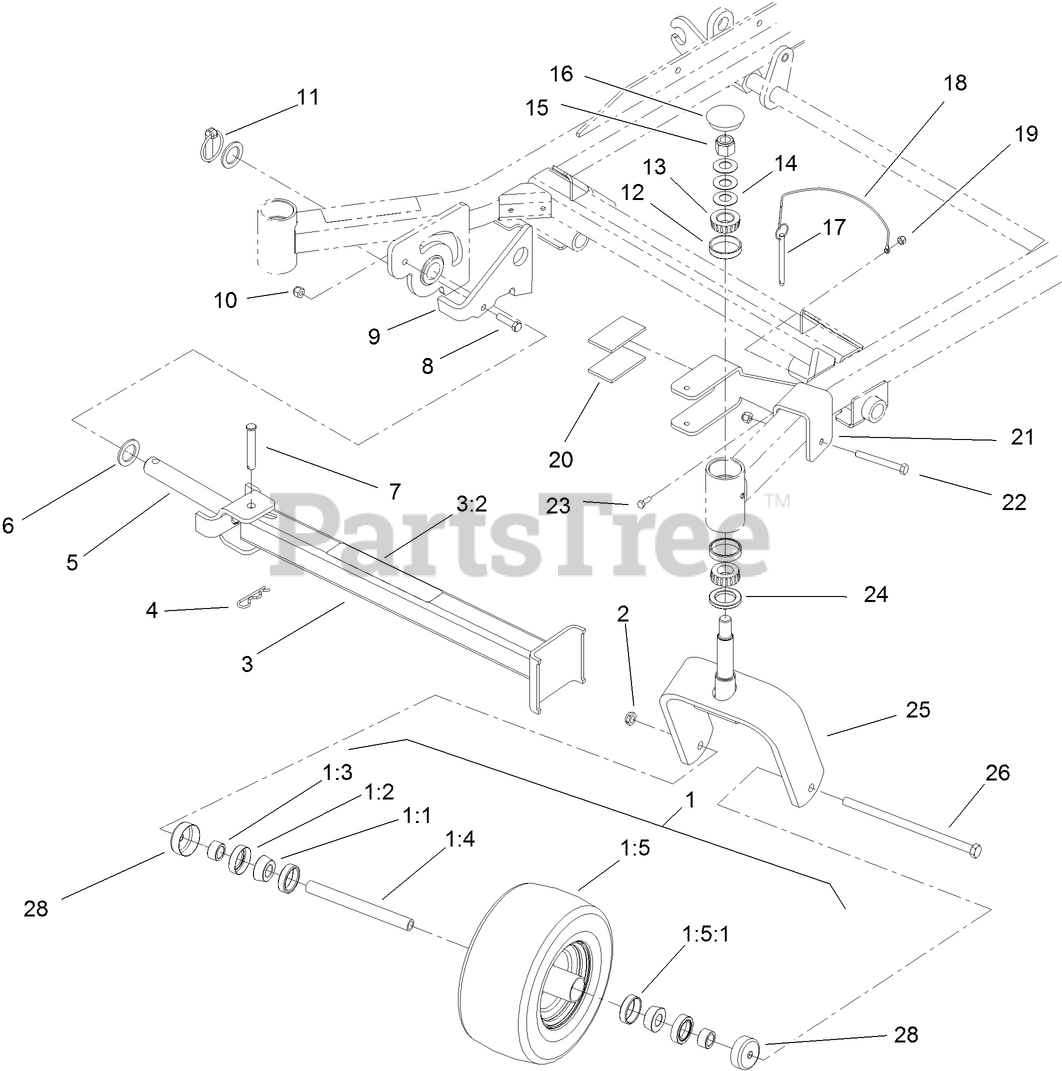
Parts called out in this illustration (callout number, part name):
1	WHEEL AND TIRE ASM
1:1	BEARING-CONE, TAPER
1:2	SEAL-CASTER
1:3	SPACER-NUT
1:4	AXLE-CASTER
1:5	WHEEL AND TIRE ASM
1:5:1	BEARING-CUP
2	NUT-LOCK, NI
3	Leg ASM
3:2	DECAL-Z STAND
4	PIN-HAIR
5	PIN-PIVOT
6	WASHER-THRUST
7	PIN-CLEVIS
8	SCREW-HH
9	BRACKET-LATCH
10	NUT-LOCK, NI
11	PIN-LYNCH
12	BEARING-CUP, TAPERED
13	BEARING-CONE, TAPERED
14	WASHER-BELLVILLE
15	NUT-LOCK, NI
16	CAP-GREASE
17	PIN-HITCH, COTTERLESS
18	LANYARD-NYLON
19	NUT-LOCK, NI
20	Cushion-Rubber
21	BRACKET-CRADLE
22	SCREW-HH
23	SCREW-HH
24	SEAL-GREASE
25	CASTER-FORK
26	Screw-HH
28	GUARD-SEAL
